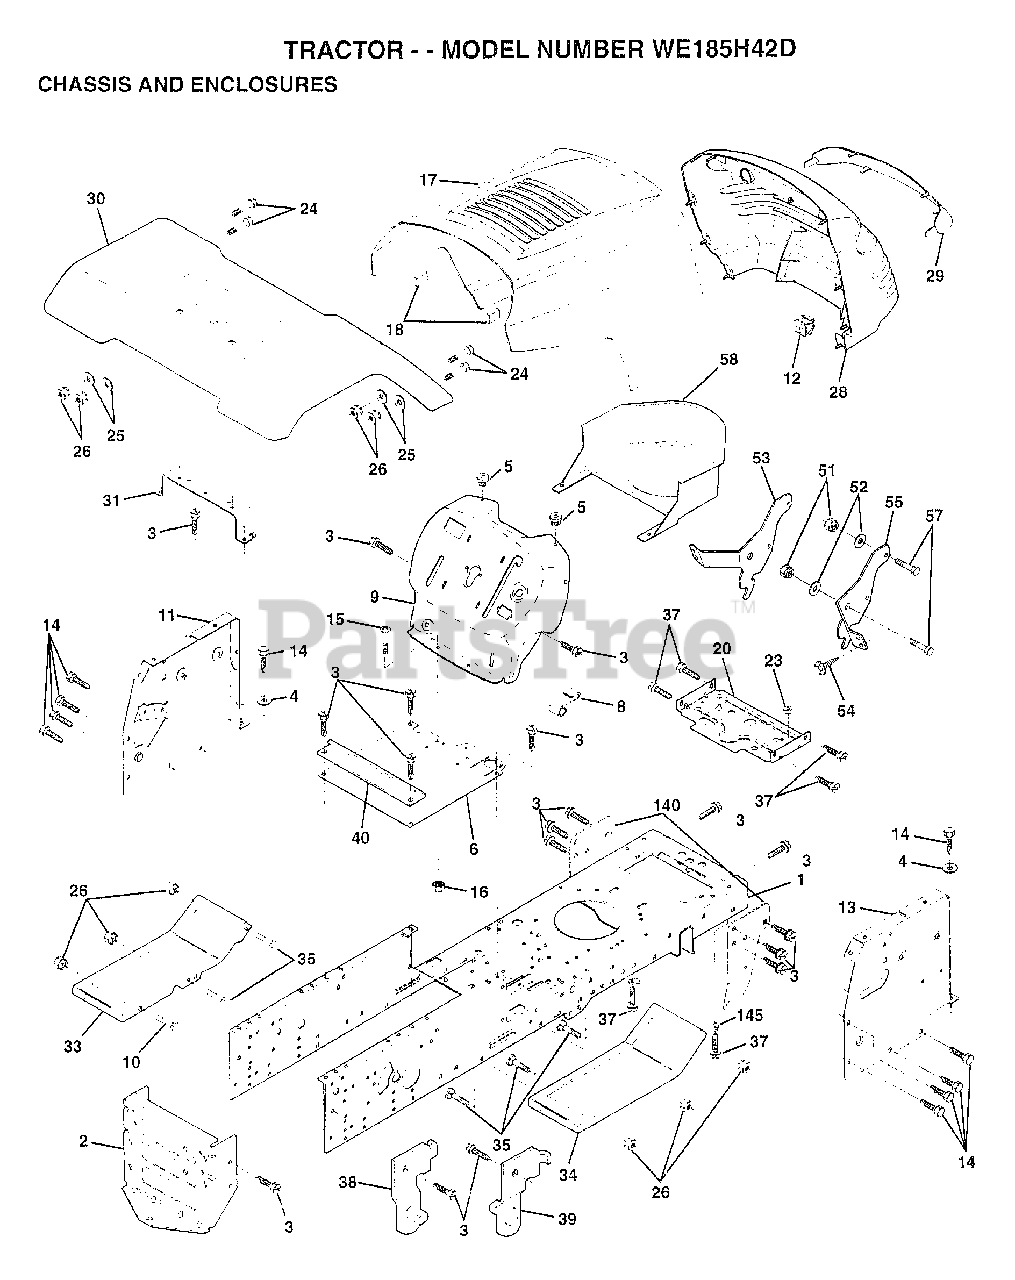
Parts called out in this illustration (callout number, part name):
3	SCREW
4	WASHER
5	BUMPER-HOOD/DASH
6	SADDLE
8	CLIP.RETAINER
9	DASH SILKSCREEN
11	"PANEL-DASH,LH"
12	CLIP.TINNERMAN
14	SCREW LT
15	SCREW
17	HOOD.STEEL.ASSY
20	"PLATE-MTG,BATT/FU"
24	BOLT
25	WASHER
26	NUT
28	GRILLE-MS428
29	LENS GRILLE
31	BRACKET SUPT FEND
33	FOOTREST.LH.LT/GT
34	FOOTREST.RH.LT/GT
35	BOLT
37	SCREW LT
38	BRACKET ASM LH
39	BRACKET ASM RH
40	SPACER FENDER LT
51	NUT
52	WASHER
53	BRACKET.GRILLE.LH
54	SCREW.HEX.WS.HD
55	BRACKET.GRILLE.RH
58	DUCT.AIR.B&S.18HP
140	BRKT SUSPENSION
145	"ROD POVOT,CHASSIS"
